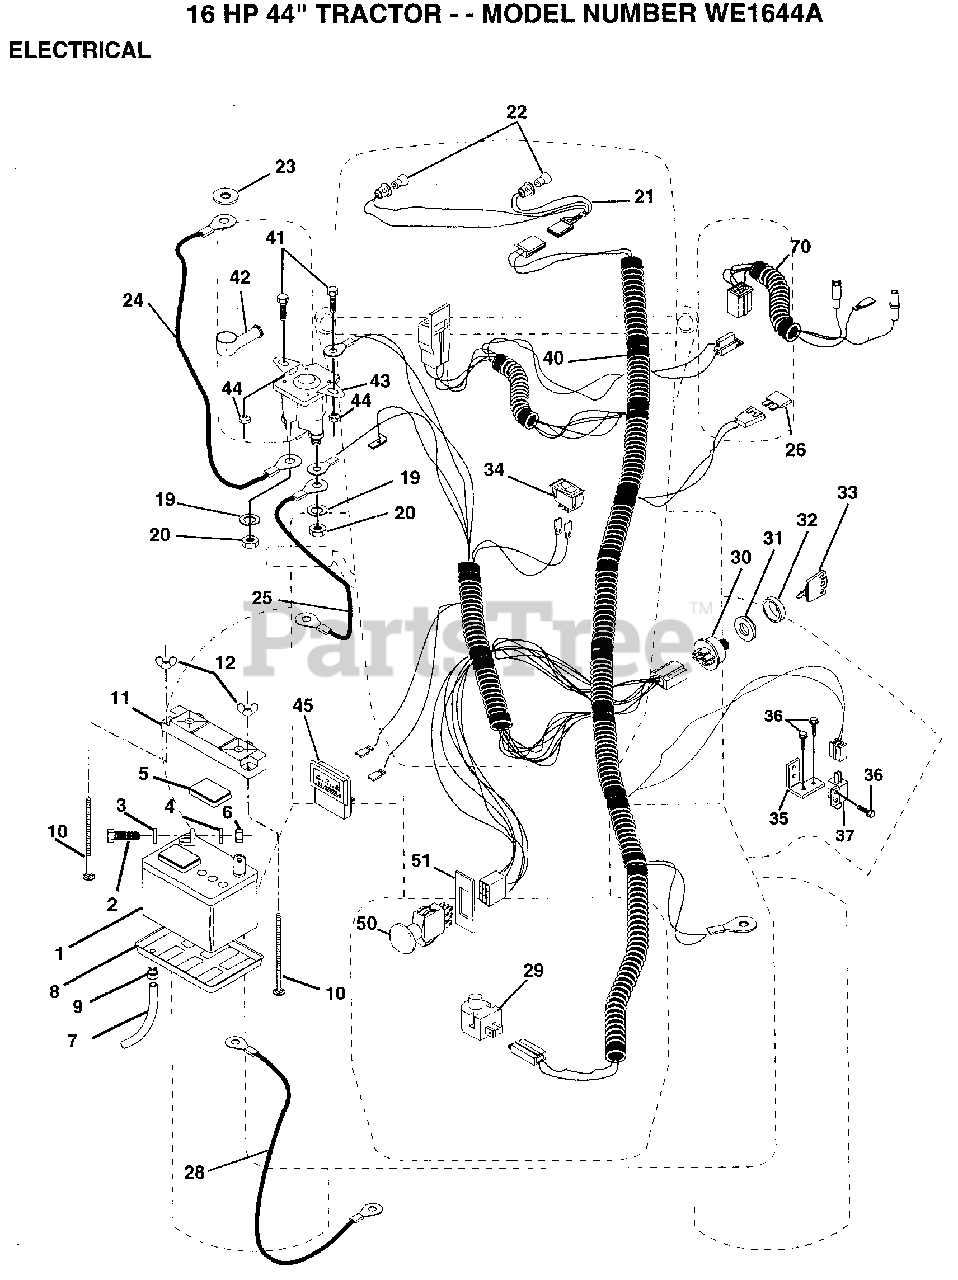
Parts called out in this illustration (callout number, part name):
2	BOLT LT
3	WASHER
4	LOCKWASHER
5	"CAP,BATTERY "
7	"DRAIN TU T, BATT"
8	"TRAY T, BATTERY"
9	HOSE CLAMP T
10	BOLT
21	"HARNESS,LIGHT SOC"
22	HEADLAMP BULB
23	LOCKWASHER
24	"CABLE T, BATTERY"
25	CABLE-BATTERY T
26	FUSE HYT
28	CABLE T
29	SWITCH SEAT
32	COVER KEY SWITCH
33	KEY MLD GEN DELTA
34	SWITCH LT
35	BRACKET LT
36	SCREW
37	SWITCH-INTER. GT
40	HARNESS IGN DASH
41	BOLT HXHD FIN
44	NUT HXKEP 1/4X20
45	AMMETER
51	RING RETAIN PTO
70	HARNESS ENG B&S
